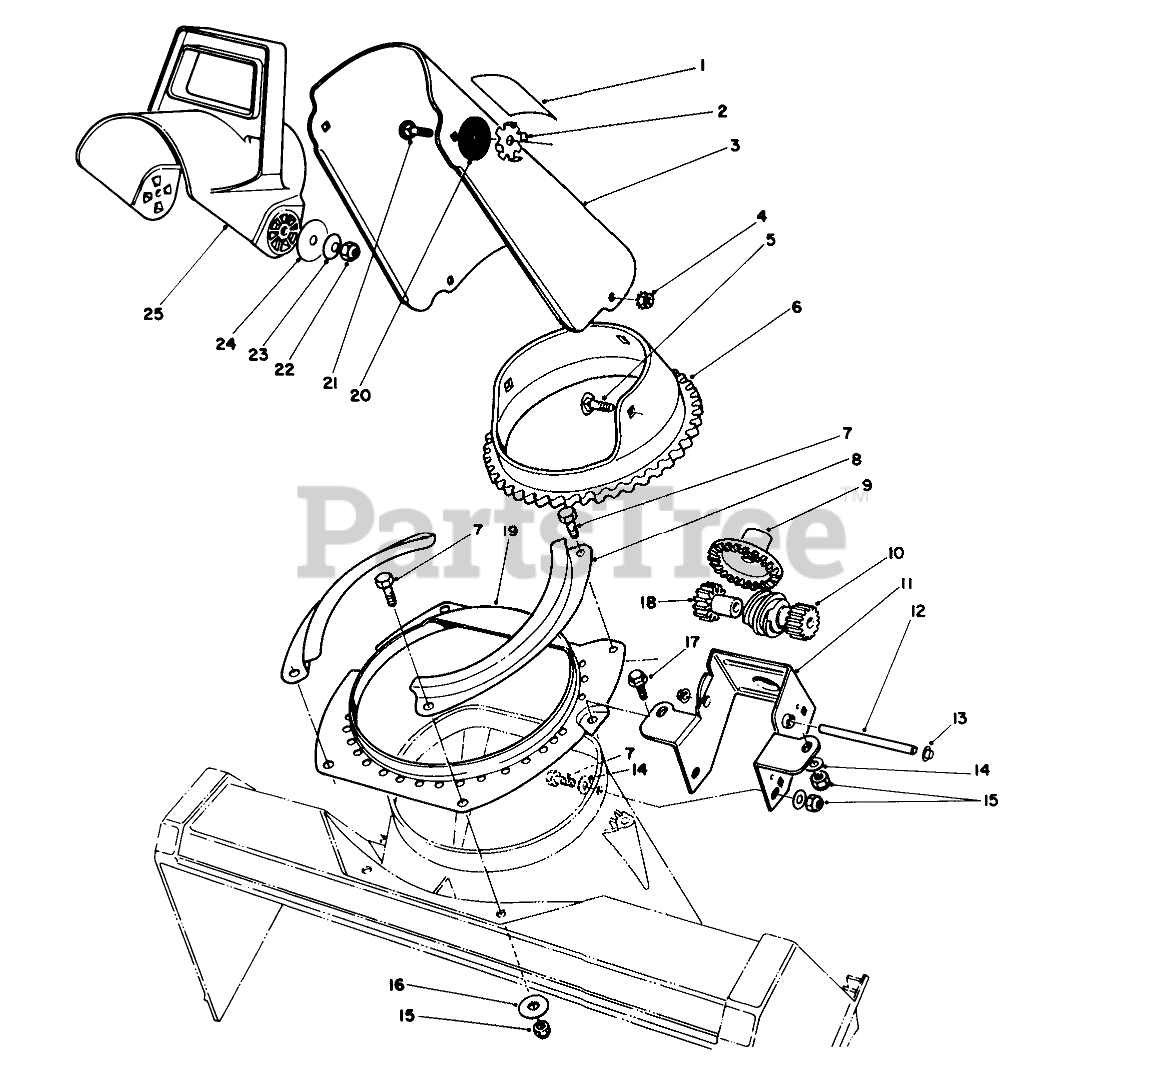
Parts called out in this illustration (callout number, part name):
1	Decal-Danger
2	PLATE-FRICTION
3	Chute-Discharge (Incl. Ref. #1: 63-3760)
4	NUT-KEPS
5	SCREW-CARR
6	RING-GEAR, CHUTE
7	SCREW-HH
8	Retainer-Chute Ring
9	GEAR-FACE
10	GEAR-SPUR/WORM
11	Bracket-Chute Gear
12	SHAFT-GEAR, WORM
13	NUT-PUSH
14	WASHER-FLAT
15	NUT-LOCK, NI
16	WASHER-FLAT
17	SCREW-PLASTITE
18	GEAR-SPUR, SPACER
19	Ring-Chute Support
20	WASHER-RUBBER
21	SCREW-CARR
22	NUT-LOCK, NI
23	WASHER-BELLEVILLE
24	WASHER-FLAT
25	CHUTE-DEFLECTOR
